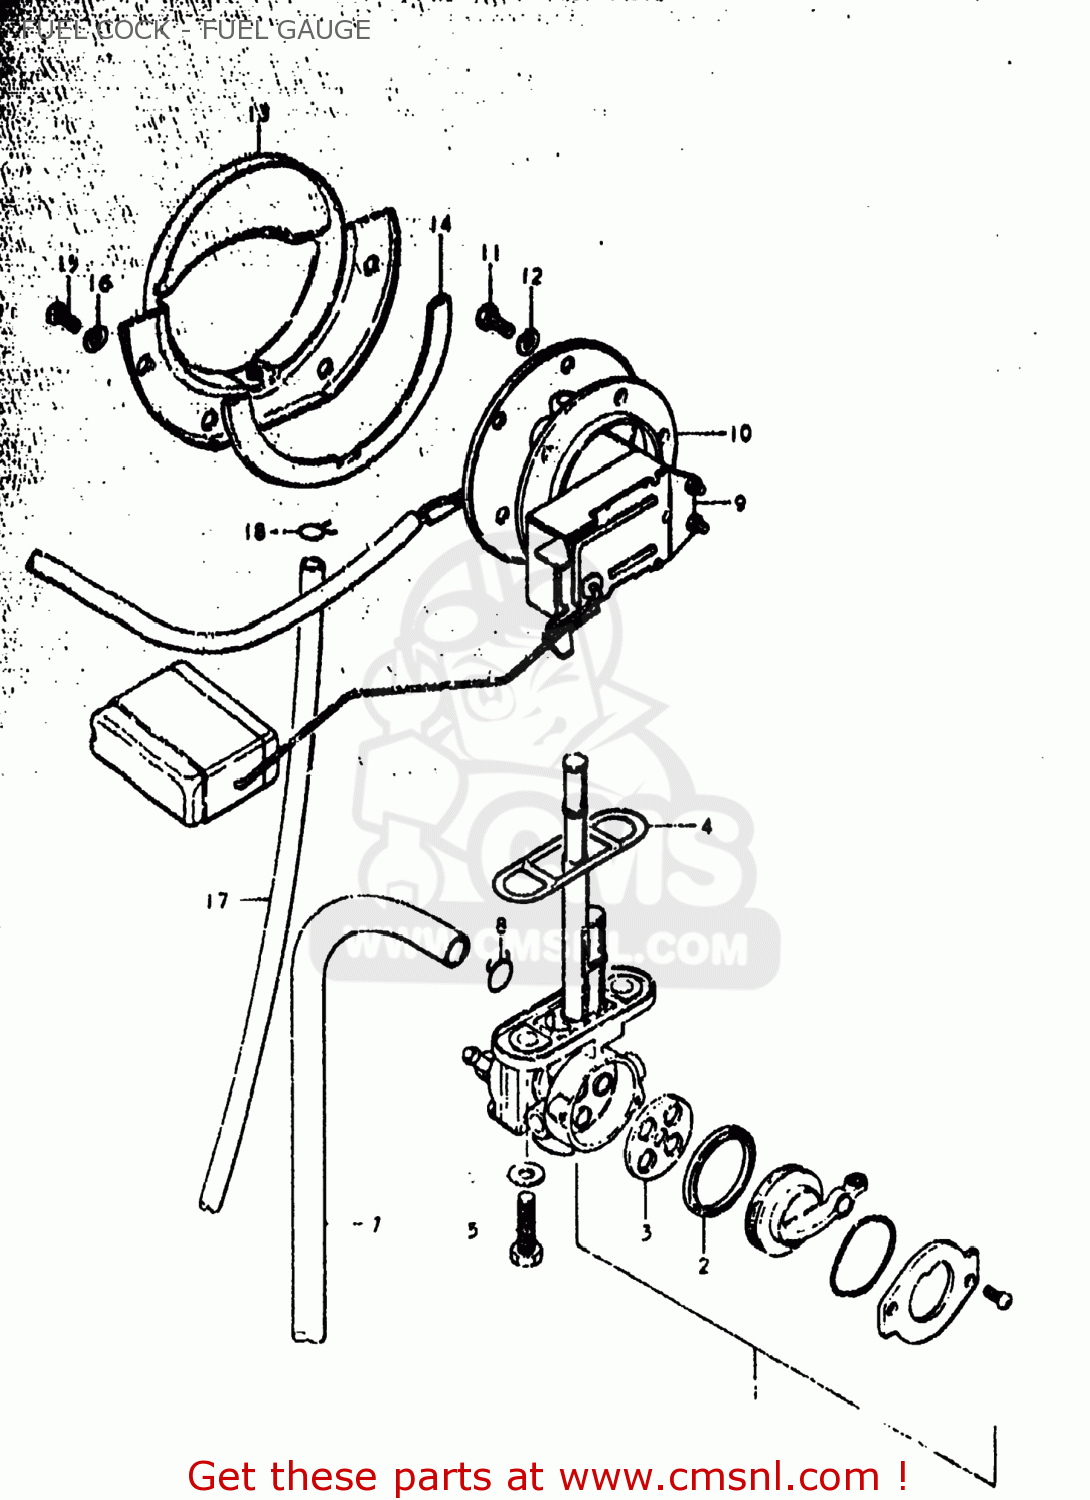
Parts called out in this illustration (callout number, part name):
1	COCK ASSY,FUEL
2	V SEAL,FUEL COCK
3	GASKET (NAS)
4	GASKET,FUEL COCK (NAS)
5	BOLT(6X20)
6	GASKET
7	HOSE
8	CLIP
9	GAUGE ASSEMBLY,FUEL LEVEL
10	GASKET,FUEL LEVEL GAUGE (NAS)
11	BOLT
12	LOCK WASHER
13	PLATE,FUEL DRAIN
14	GASKET,FUEL DRAIN PLATE (NAS)
15	SCREW
16	LOCK WASHER
17	HOSE
18	CLIP
